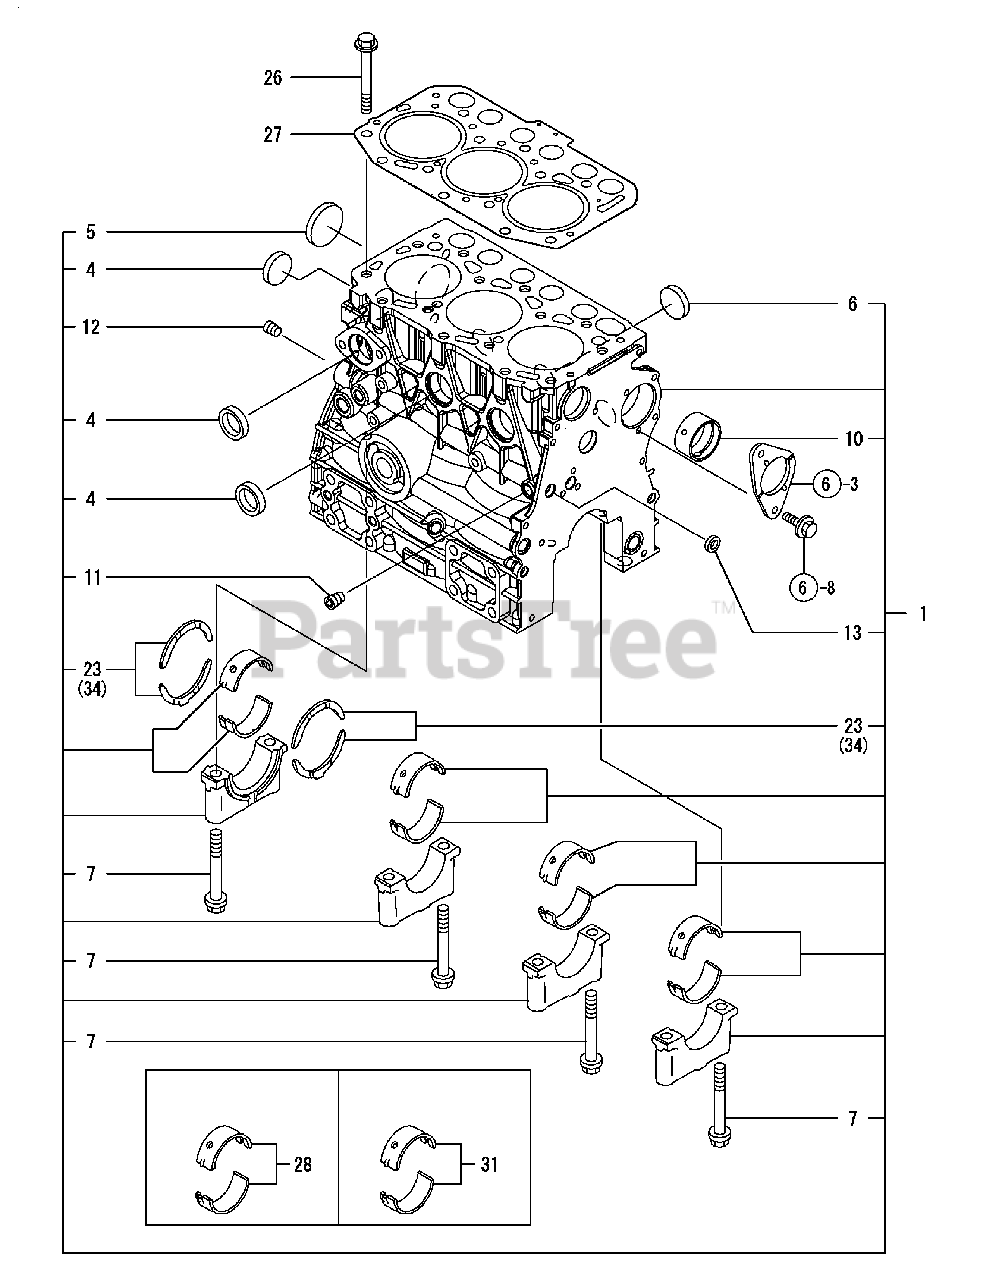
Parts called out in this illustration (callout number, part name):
1	Block Assembly, Cylinder
10	Bush, Camshaft
23	Bearing, Thrust
26	Bolt, Cylinder Head
27	Gasket, Cylinder Head
28	Main Bearing Set
34	Bearing, Thrust
